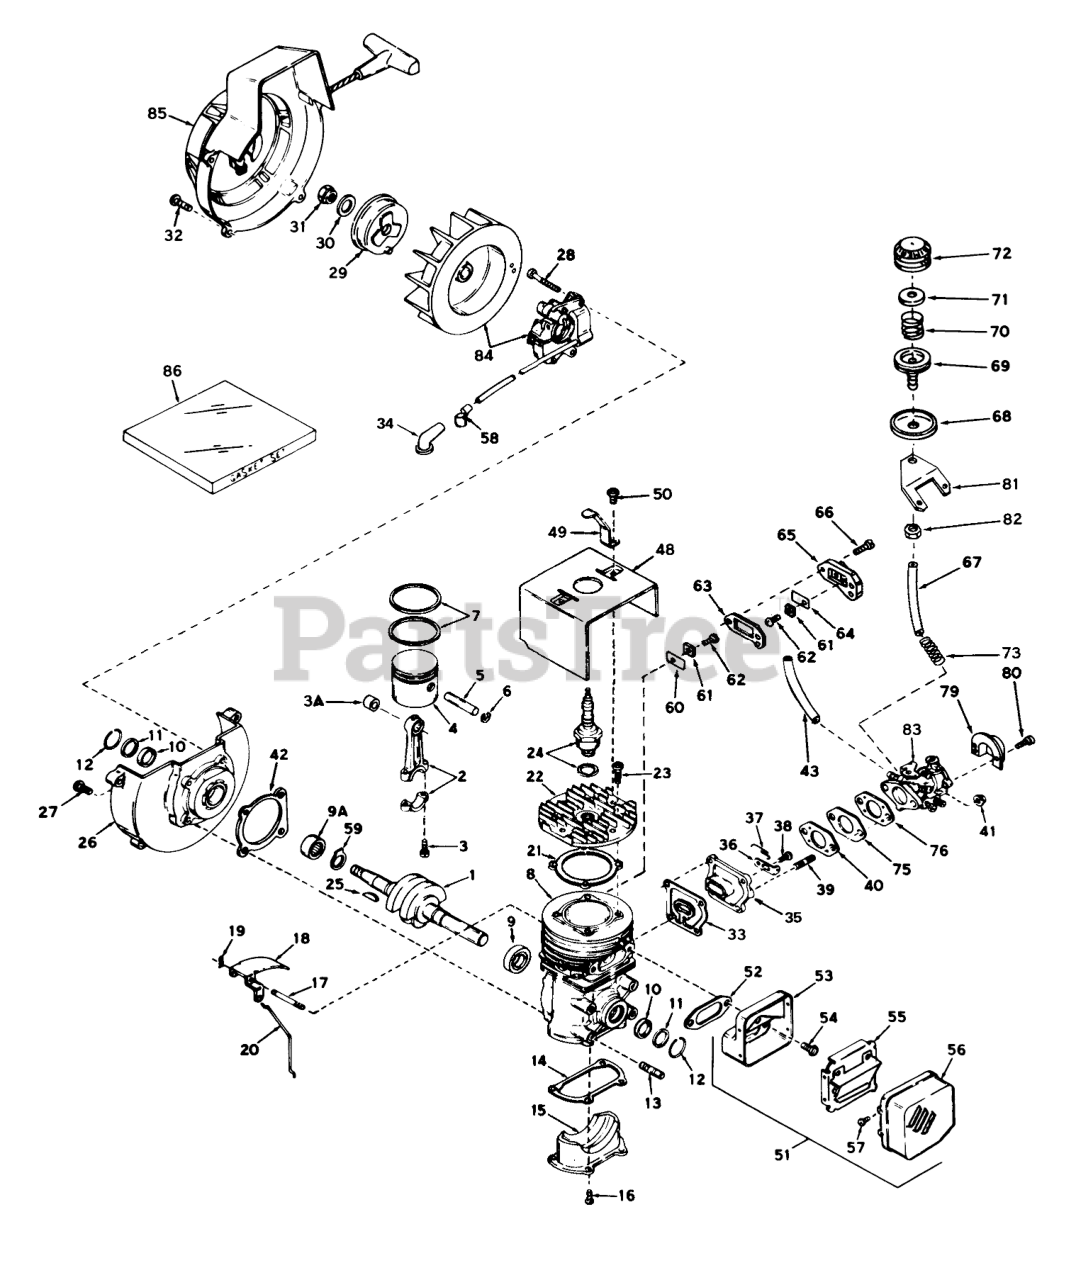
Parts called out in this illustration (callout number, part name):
1	Crankshaft
2	Rod Assembly, Connecting (Incl. Nos. 3 & 3A)
3	Bolt-Rod, Connecting
3A	Bearing-Cartridge
4	Piston
5	Pin, Piston
6	Ring-Retaning
7	Ring Set
8	Block Assembly, Cylinder (Incl. Nos. 9, 10-13 & 17)
9	Bearing Ball
9A	Bearing-Cartridge
10	Seal, Crankshaft
11	Retainer, Crankshaft Seal
12	Spring, Crankshaft Seal
14	Gasket, Cover
15	Plate, Cover
16	Screw (T-25, 10-24 x 1/2)
17	Shaft, Air Vane
18	Vane Assy, Air
19	Clip,Air Vane
20	Link Governor
21	Gasket, Cylinder Head
23	Screw (T-30, 1/4-20 x 3/4)
24	Plug, Spark (J17LM or equiv.)
25	Key, Woodruff
26	Base Assembly, Shroud (Incl. Nos. 9A-12)
27	Screw
29	Cup, Starter
30	Washer, Flat
31	Nut, Flywheel
32	Screw (T-30, 1/4-20 x 3/4)
33	Gasket, Port
34	51005 GIL.ROTARY TI
35	Adapter, Cover
36	Lever, Adjusting
37	Spring, Adjusting Lever
38	Screw
40	Gasket, Carburetor 1/8" thick)
41	Locknut
42	Gasket, Shroud Base
43	Line-Fuel (8.62)
48	Shroud, Cylinder
49	Lever, Stop
50	Screw (1/4-20 x 1/2)
51	Muffler Assembly (Incl. Nos. 53-57)
52	Gasket-Muffler
53	Base-Muffler
54	Screw
55	Baffle, Muffler
56	Cover, Muffler
58	Terminal, Lead wire
59	Washer, Thrust
60	Reed, Compression Release
61	Plate, Reed Hold Down
63	Gasket, Compression Release
64	Reed, Compression Release
65	Cover, Compression Release
66	Screw
67	Line, Primer
68	Retainer, Primer Bulb
69	Body Primer
70	Spring, Primer Bulb
71	Washer, Primer Bulb
72	Bulb, Primer
73	Spring, Primer line support
76	Gasket, Carburetor (1/16"thick)
79	Baffle-Carburetor
81	Mounting Bracket, Primer
82	Hex nut
83	Carburetor
84	BRACKET S
85	Shroud & Starter Assy.
86	Gasket Set
